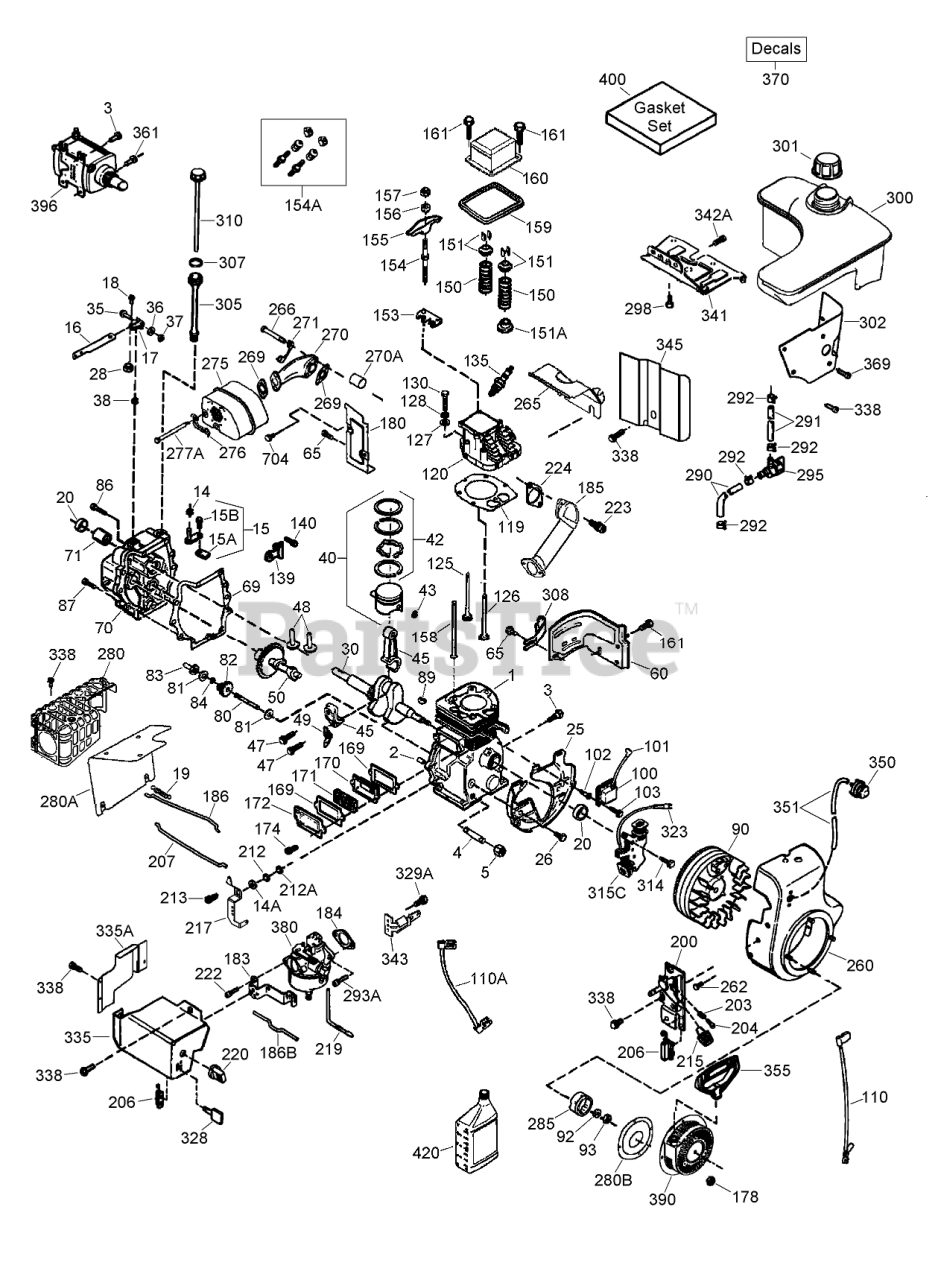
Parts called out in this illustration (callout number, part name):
178	Nut and Lock Washer (1/4-28)
180	Extension-Housing, Blower
183	Bracket-Choke
184	Gasket-Carburetor To Intake Pipe
185	Pipe-Intake
186	Link-Governor
186B	Spring-Choke
200	Bracket-Control
203	Spring-Compression
204	Screw (T-10, 5-40x7/16)
206	Terminal (Shorting On-Off)
207	Link-Throttle
212	Bushing
212A	Washer
213	Screw (10-24 X 29/32)
215	Knob-Control, Speed
217	Lever-Bellcrank
219	Rod-Choke
220	Knob-Control, Choke
222	Screw (10-32 X 15/32)
223	Screw (T-30, 5/16-18 X 7/8)
224	Gasket-Pipe, Intake
260	Housing-Blower
262	Screw (5/16-18x9/16)
265	Cover-Head, Cylinder
266	Screw (5/16-18 X 1-9/32) (Manifold)
269	Gasket-Manifold, Exhaust
270	Manifold, Exhaust
270A	Liner-Port, Exhaust
271	Plate-Locking (Manifold)
275	Muffler (With Mounting Brackets)
276	Plate-Locking
277A	Screw (5/16-18 X 4-1/2) (Muffler)
280	Shield-Heat (Must have Muffler 37264)
280A	Shield-Heat, Radiation
280B	Baffle-Restrictor, Air
285	Cup-Starter
290	Line-Fuel, Low Permeation (32.0 Length)
291	Line-Fuel, Low Permeation (8.62)
292	Clamp-Line, Fuel
293A	Screw (T-30, 1/4-20 X 27-32)
295	Valve-Shut Off, Fuel (Includes 292)
298	Screw (1/4-15x7/8)
300	Tank-Fuel (Includes 292, 301)
301	Cap-Fuel (Black) (1-1/2 I D)
302	Extension-Tank, Fuel
305	Tube-Fill, Oil
307	O-Ring
308	Clip-Tube, Fill
310	Dipstick
314	Screw (1/4-20 x 3/4)
315C	Coil-Alternator, 18 Watt
323	Terminal (single pin)
328	Key-Ignition
329A	Screw (8-32 x 23/64)
335	Cover-Carburetor (Front)
335A	Cover-Carburetor (Side)
338	Screw (10-32 x 1/2)
341	Bracket-Tank, Fuel (Lower)
342A	Screw (5/16-18 X 7/8)
343	Bracket-Switch, Key (Includes 329A)
345	Baffle-Heat
350	Primer Asm (Vented snap-in)
351	Line-Primer
355	Handle-Starter, Mitten Grip
361	Screw (T-30, 1/4-20x15/32)
369	Screw (12-16 x 5/8)
370	Decal-Primer, International Symbol
370	Instruction Decal-Caution, read owner manual
370	Decal-Tecumseh Logo for Top of Recoil Starter
370	Decal-Choke
370	Decal-Start Button, Electric
370	Decal-Hot Surfaces
380	Carburetor Asm (Includes 184)
390	Starter-Rewind
396	Electric Starter Motor ASM (220 Volt)
400	Gasket Set
420	Oil-Engine, S A E 5W30
704	Screw (1/4-20 X 5/8)
